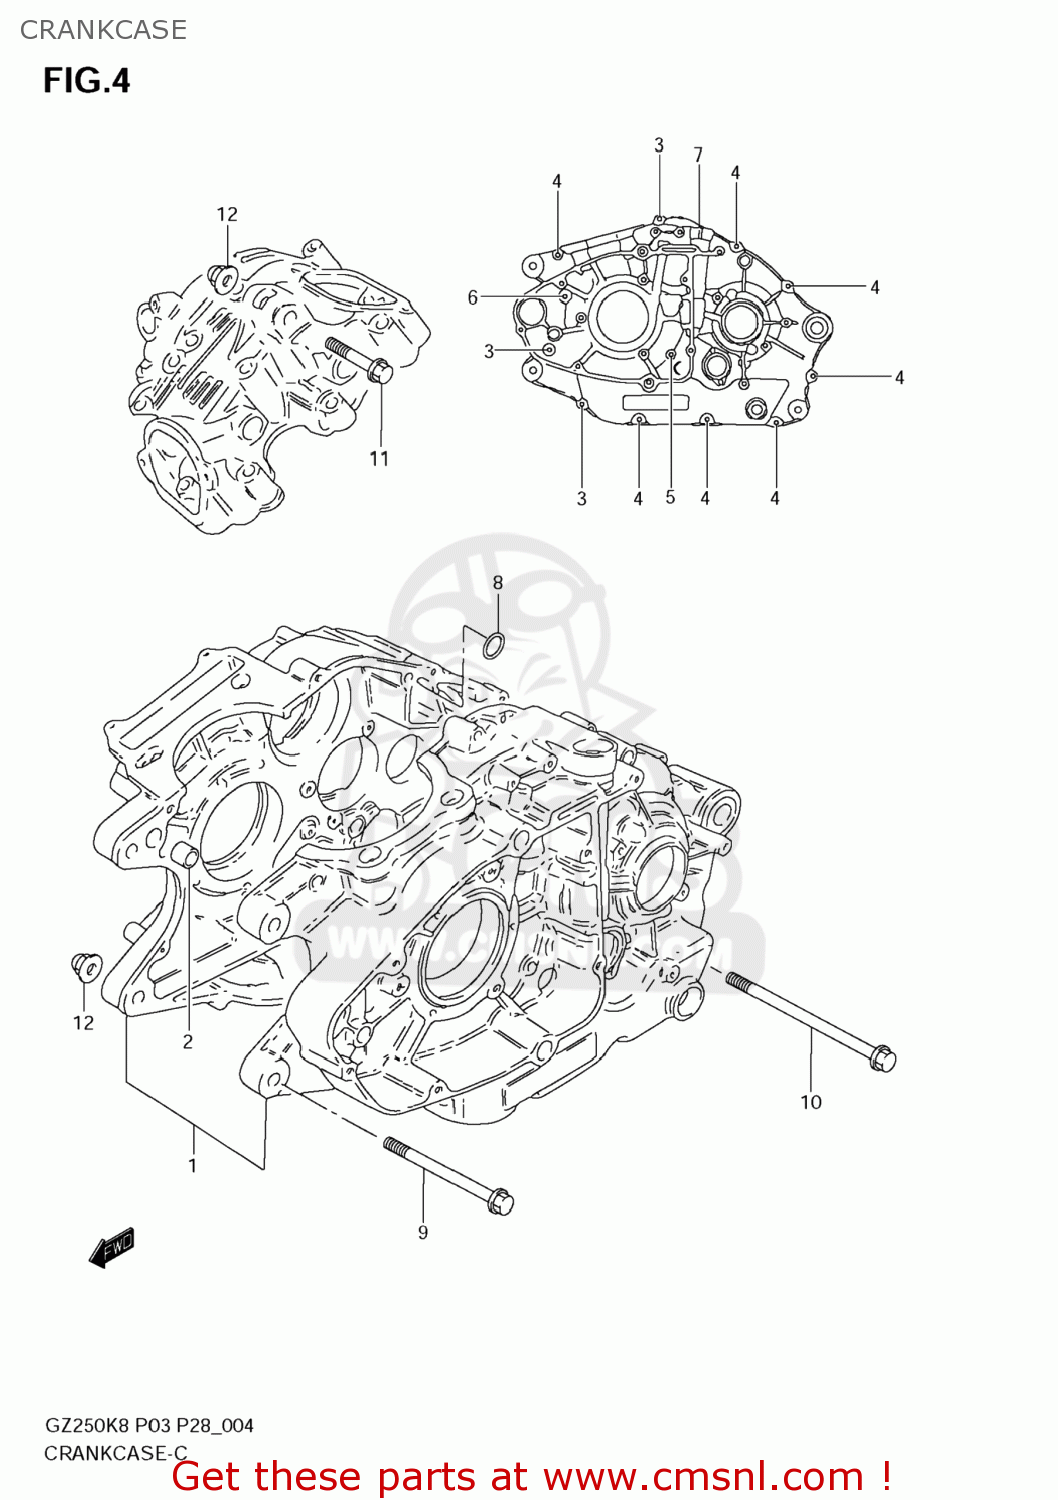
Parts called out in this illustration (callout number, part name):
1	CRANKCASE SET
2	PIN
3	BOLT
4	BOLT
5	BOLT
6	BOLT
7	BOLT
8	O-RING,OIL LEVEL GAUGE
9	BOLT(8X67)
10	BOLT(8X100)
11	BOLT(8X50)
12	NUT
